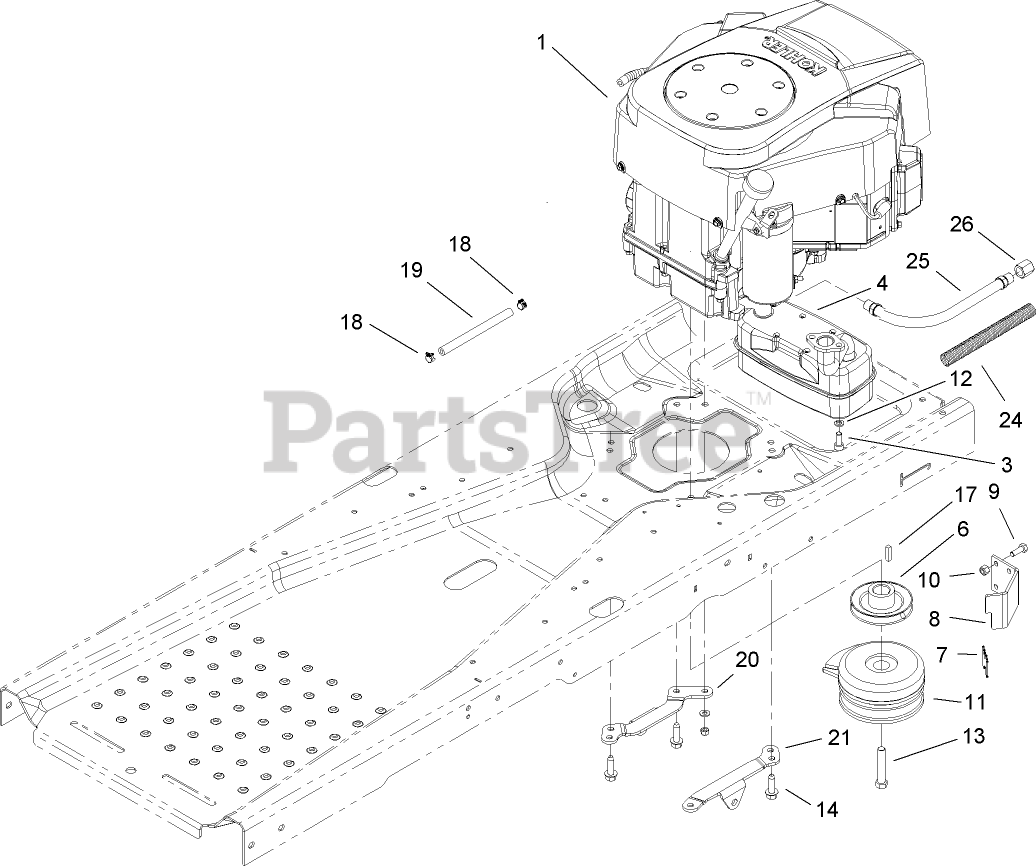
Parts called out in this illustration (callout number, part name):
1	Loose Parts Package
3	SCREW-HSH
8	STOP-CLUTCH
9	SCREW-HH
10	NUT-LOCK, NI
11	CLUTCH-ELECTRIC, PTO
12	WASHER-LOCK
13	SCREW-HH
14	SCREW-THD
18	CLAMP-HOSE
19	HOSE-FUEL
20	SUPPORT-HYDRO, RH
21	SUPPORT-HYDRO, LH
24	TUBING-CONVOLUTED
25	HYD HOSE ASM
26	CAP-PIPE
